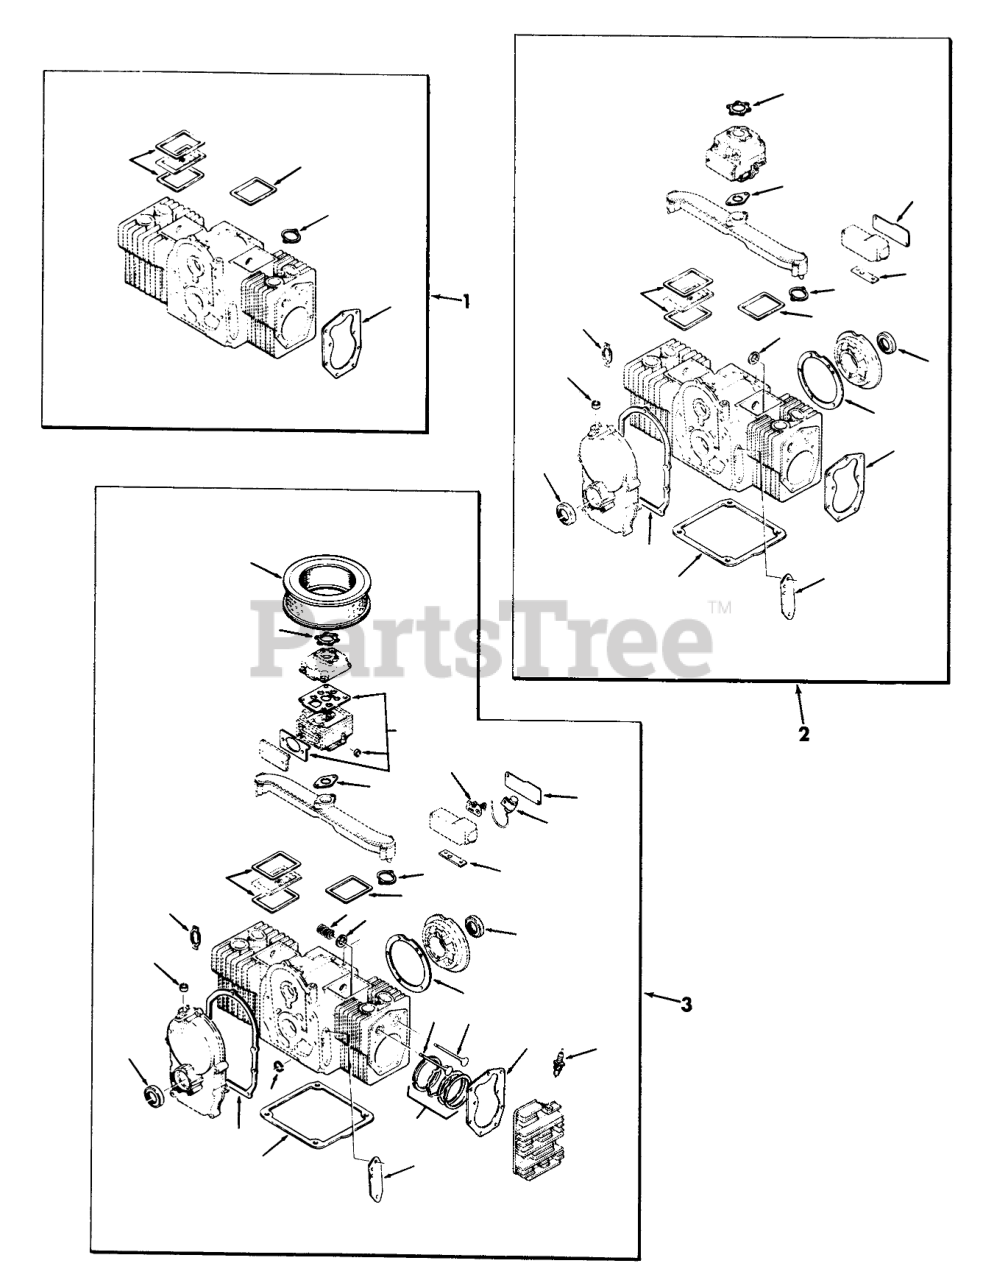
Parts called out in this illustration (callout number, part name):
1	"S" Hook
2	Engine, Complete
3	Overhaul Kit
